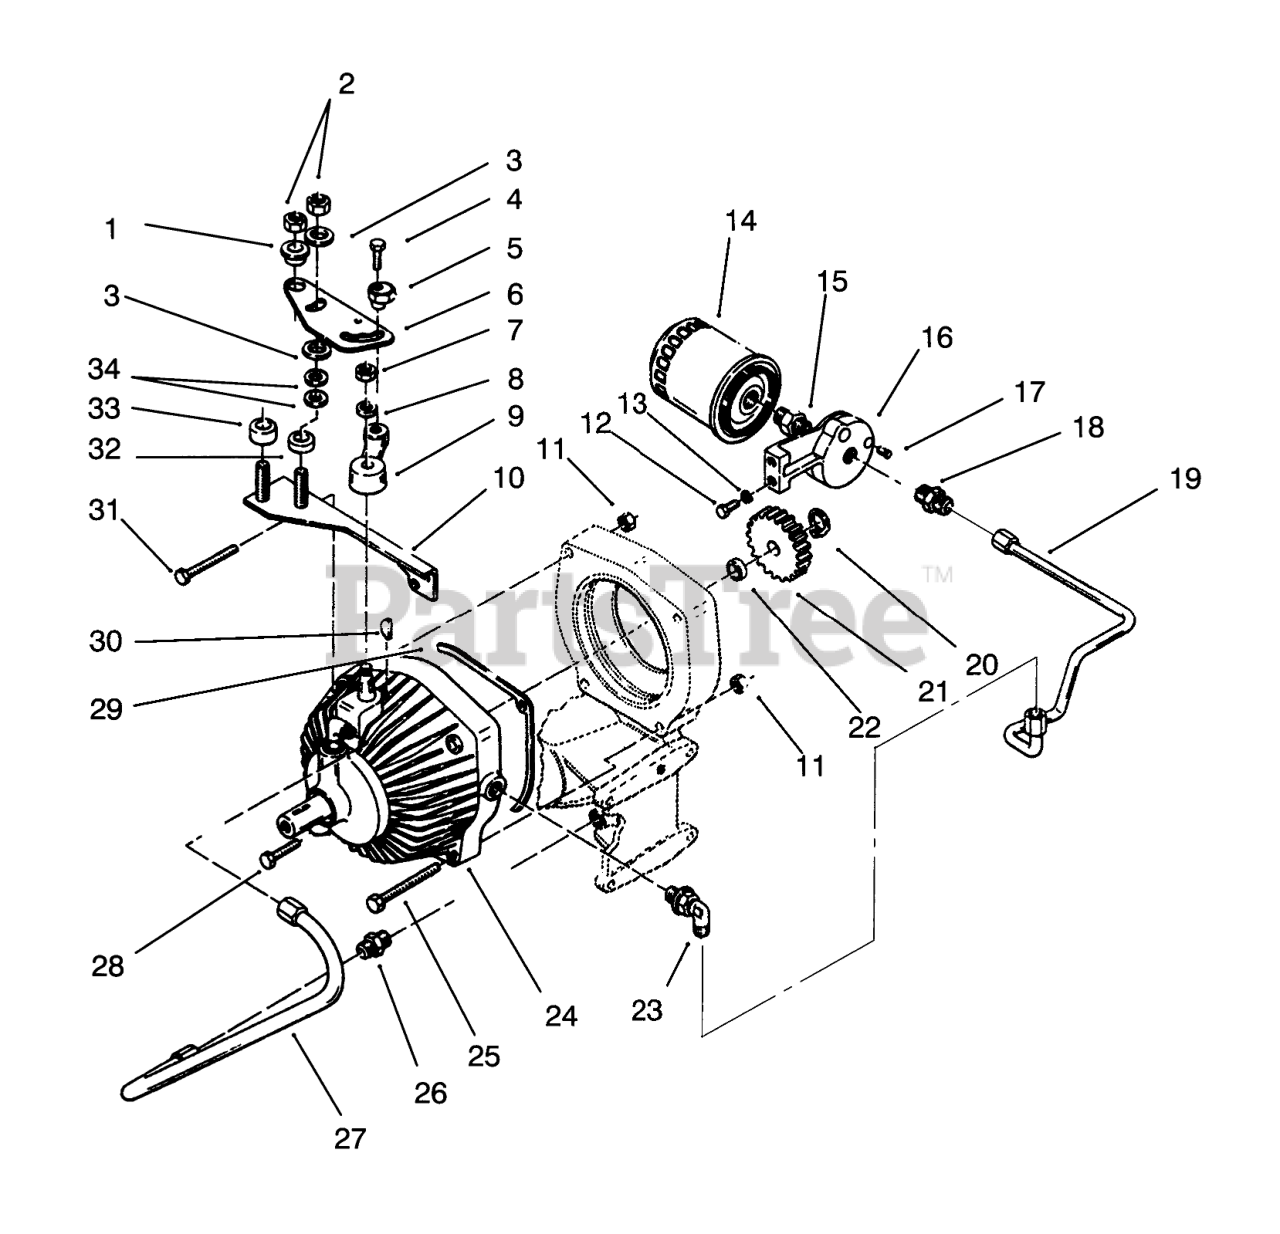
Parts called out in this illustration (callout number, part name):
1	CAM-SPACER
3	FRICTION WASHER
4	SCREW-HH
6	CAM-SPEED CONTROL (NS)
7	NUT-LOCK, NI
8	NUT-LOCK, NI
9	ARM-SPEED CONTROLB
10	ASSY-PLATE B
11	NUT-LOCK, NI
12	SCREW-HH
13	WASHER-LOCK
14	OIL FILTER ASM
15	FITTING
16	BASE-FILTER
18	FITTING
19	ASS'Y-TUBE FILTER
20	RING-SNAP, EXTERNAL
21	GEAR 20 TEETH DRIVE
22	SPACER GEAR
23	ELBOW
24	Pump & Motor
25	SCREW-HH
26	FITTING-TUBE
27	ASSY-TUBE SUCTION
29	GASKET
30	KEY-WOODRUFF
31	SCREW-HH
32	SPACER-FRICTION
33	SPACER-PIVOT
34	WASHER-SPRING DISC
